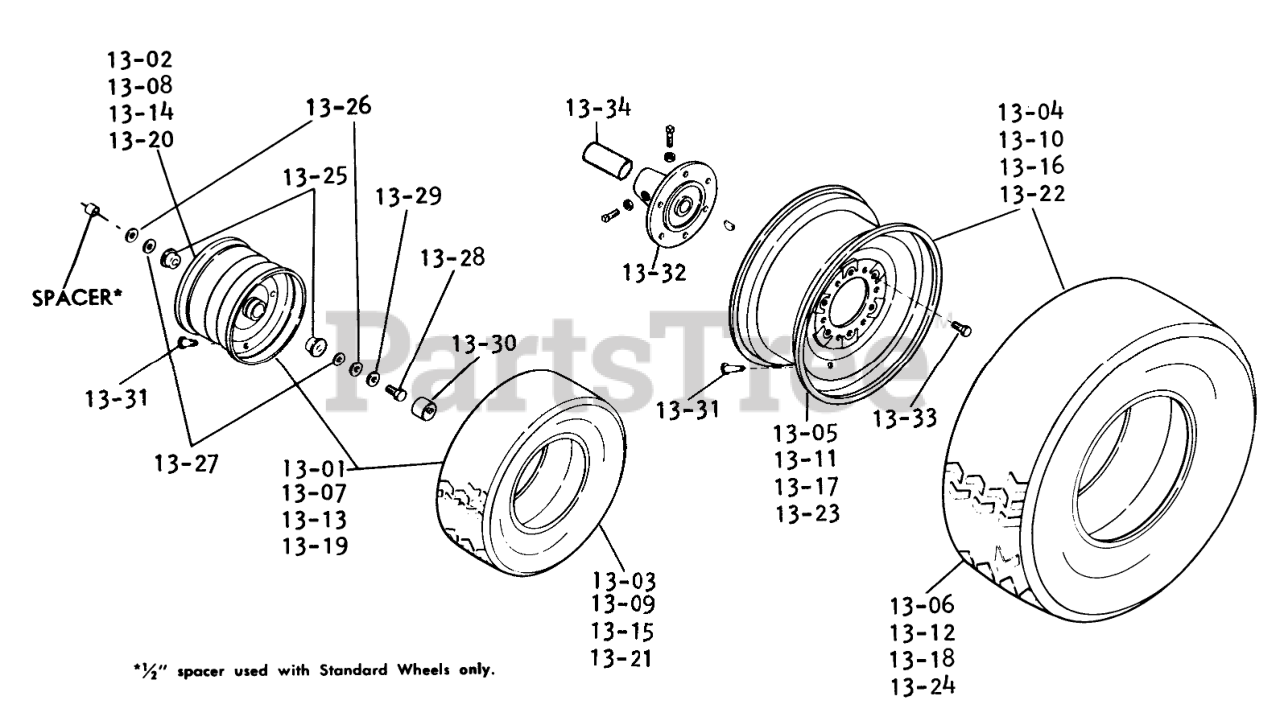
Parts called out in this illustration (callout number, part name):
13-01	ASSY-WHEEL
13-02	Wheel
13-03	Tire 18 X 850-8 Staight Rib
13-04	Rear Wheel and Tire Assy Turf
13-05	Rear Wheel
13-06	Tire 27 x 9.50-15
13-07	ASSY-WHEEL
13-08	Wheel
13-09	Tire 18 X 850-8 Staight Rib
13-10	Rear Wheel & Tire Turf
13-11	Wheel 12 x 10.5 PC
13-12	Tire, Extra Width Traction
13-13	ASSY-WHEEL
13-14	Wheel
13-15	Tire 18 X 850-8 Staight Rib
13-16	Wheel & Tire Assy.-Rear 27 X 8.50-15
13-17	Rear Wheel
13-18	Rear Tire 27 x 8.50-15 Cleat
13-19	ASSY-WHEEL
13-20	Wheel
13-21	Tire 18 X 850-8 Staight Rib
13-22	Rear Wheel & Tire Cleat
13-23	Wheel 12 x 10.5 PC
13-24	Tire, Extra Width Cleat
13-25	BEARING WHEEL
13-27	Washer
13-28	Bolt
13-29	WASHER
13-30	HUBCAP
13-31	VALVE
13-32	REAR HUB R
13-33	LUG BOLT WHEEL 7/162
13-34	Axle Cover Tube
